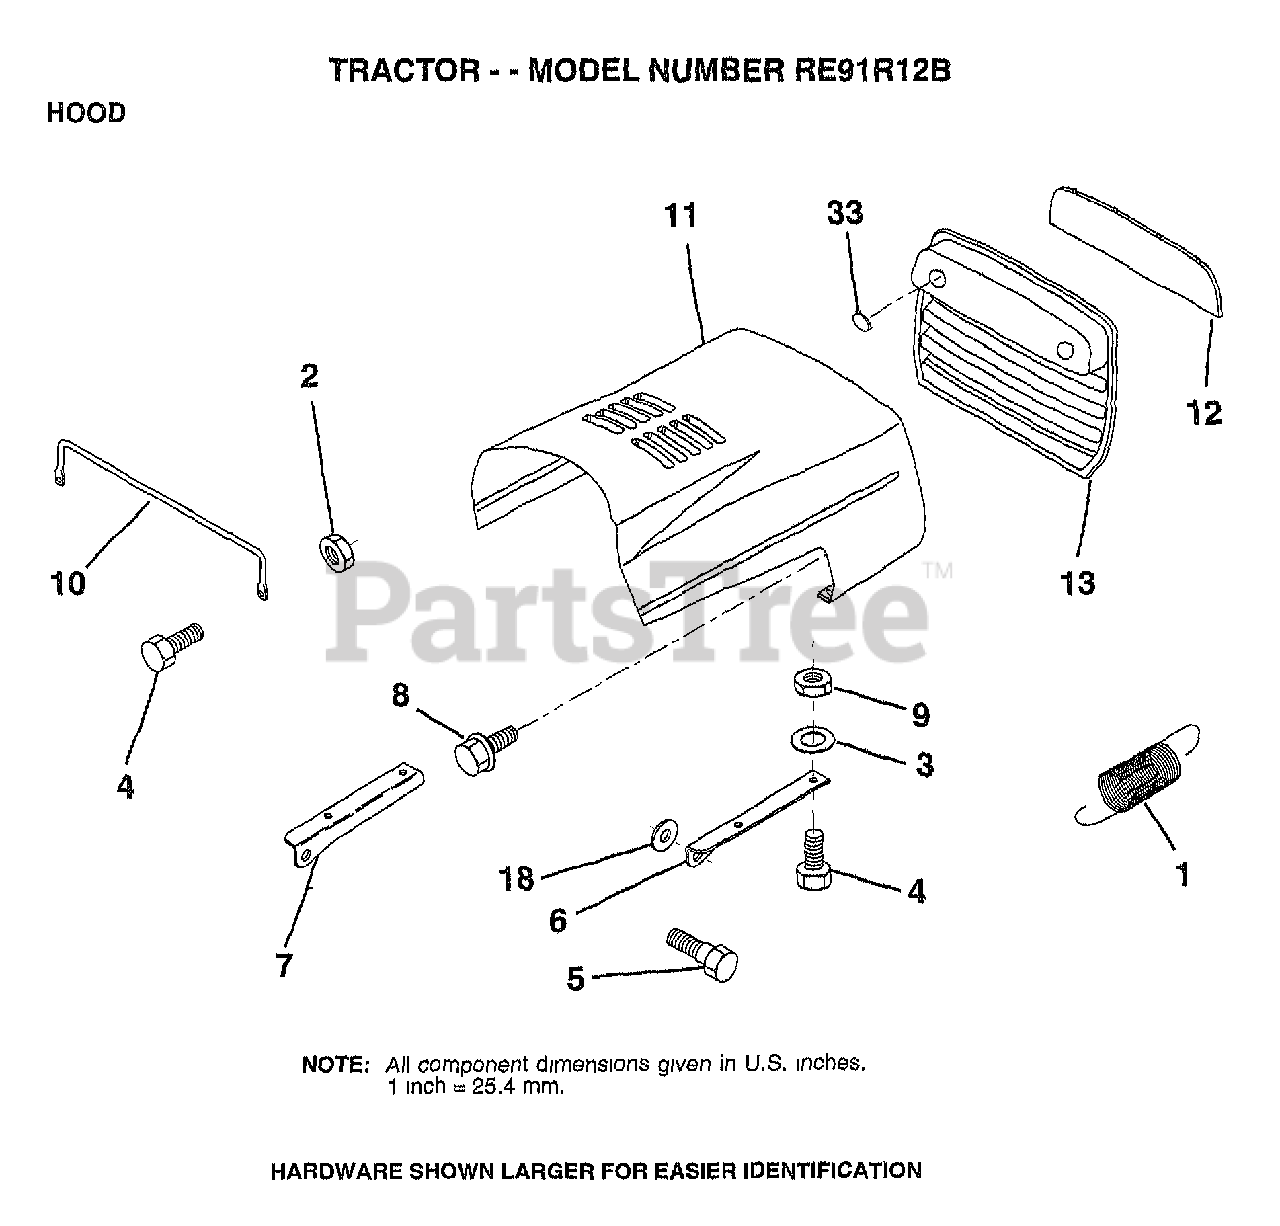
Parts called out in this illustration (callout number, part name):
1	EXT SPRING
2	NUT
3	WASHER
5	BOLT.SHLD.5/16-18
6	BRKT HOOD RH
7	BRKT HOOD LH
8	SCREW SLTD HXHD
9	NUT
10	"BRACE,HOOD"
11	HOOD
12	LENS
13	GRILL
18	WASHER
